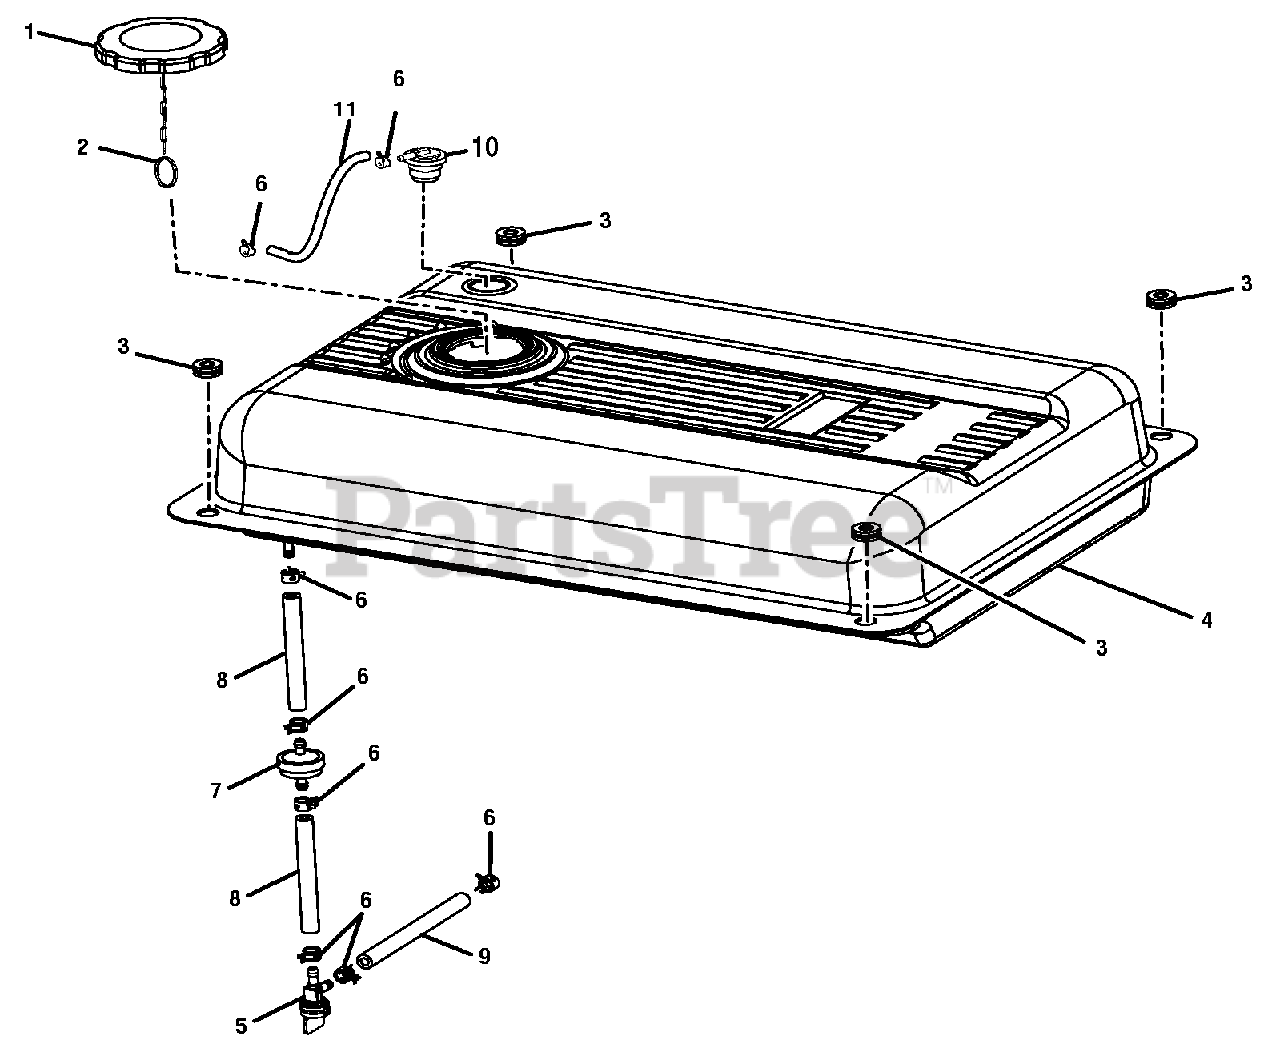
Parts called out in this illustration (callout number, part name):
1	Fuel Tank Cap
2	Ring Clip
3	Bushing w/Insert
4	Fuel Tank
5	Fuel Valve
6	Fuel Line Clamp (1/2 in.)
7	Fuel Line Filter
8	Fuel Line (1/4 in.)
9	Fuel Hose (5 mm)
10	Vapor Vent
11	Vapor Hose
